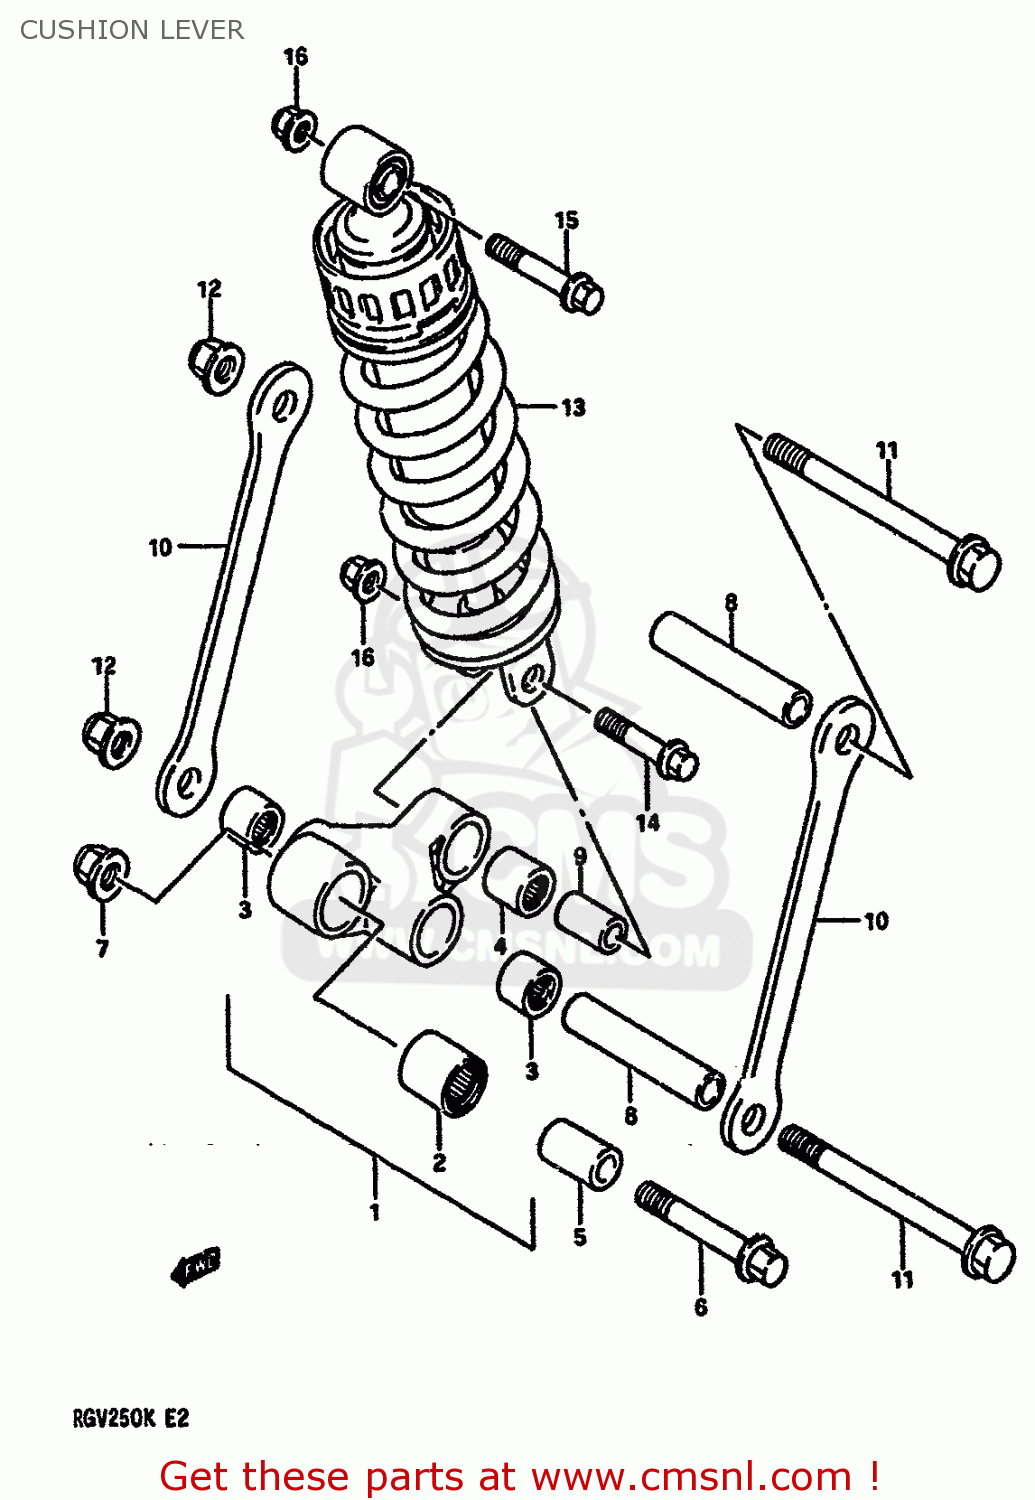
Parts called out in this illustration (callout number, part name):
1	LEVER SET,REAR CUSHION
2	BEARING(20X27X30)
3	BEARING(17X24X20)
4	BEARING(17X24X26)
5	SPACER,RR CUSHION LEVER FR
6	BOLT,RR CUSHION LEVER FR
7	NUT 12MM
8	SPACER(12X17X85)
9	SPACER,RR CUSHION LEVER
10	ROD,RR CUSHION
11	BOLT(12X115)
12	NUT 12MM
13	ABSORBER ASSY,REAR SHOCK
14	BOLT(10X52)
15	BOLT(10X75)
16	NUT
